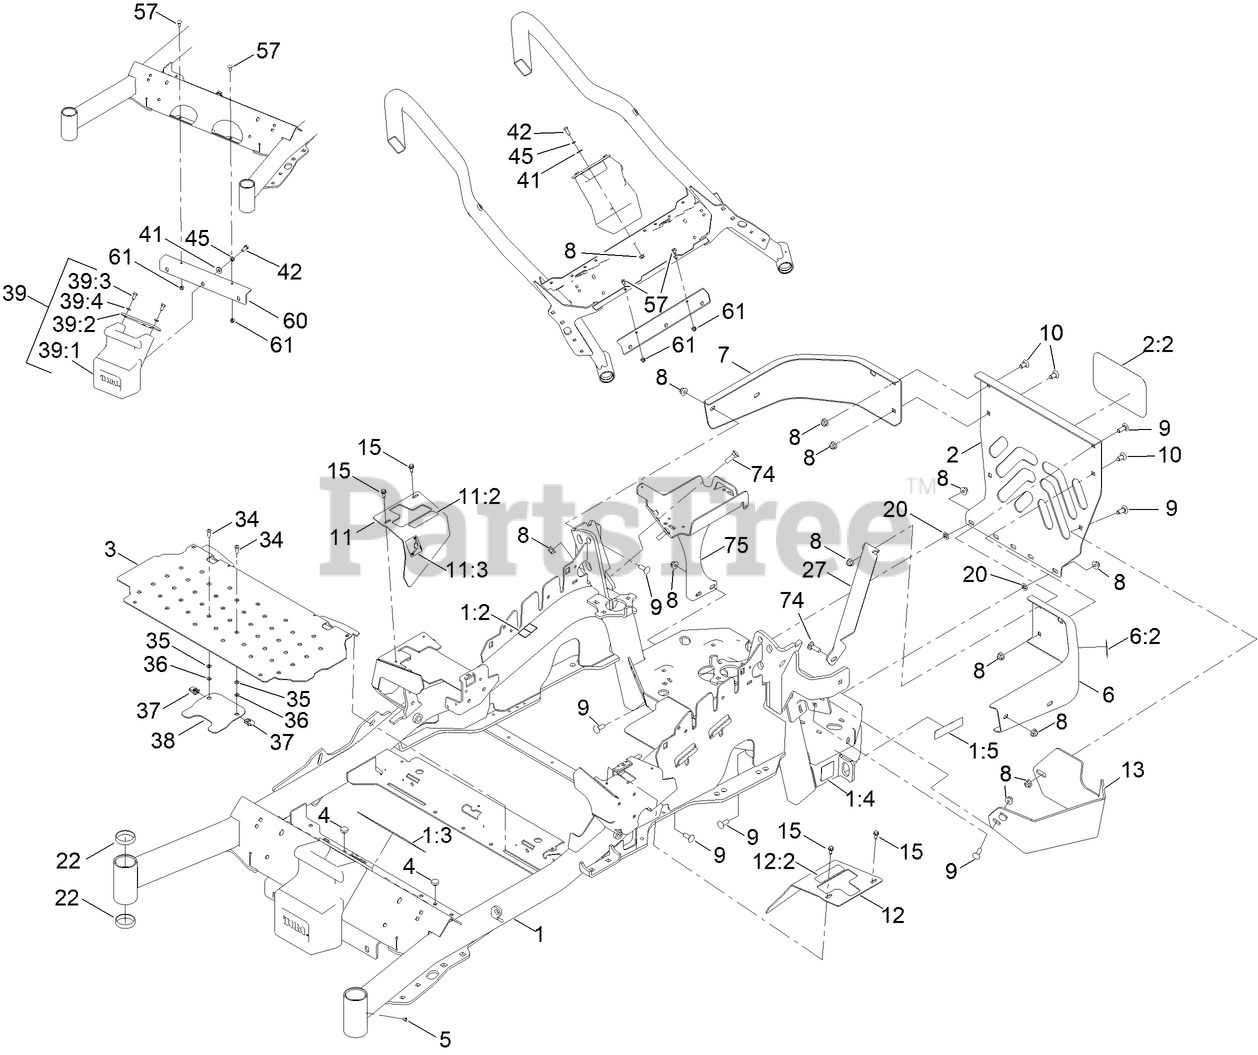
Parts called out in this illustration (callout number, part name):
1	MAINFRAME SERVICE ASM - RD
1:2	DECAL-WARNING
1:3	DECAL-DANGER
1:4	DECAL-HAZARD, PINCHED FINGER
1:5	DECAL-ARRESTOR, SPARK
2	REAR GUARD ASM
2:2	DECAL
3	FLOORPAN
4	BUMPER
6	LH BUMPER ASM
6:2	DECAL-WARNING
7	BUMPER-RH
8	NUT-HF, NI
9	SCREW-CARR
10	SCREW-CARR
11	RH MOTION CONTROL COVER ASM
11:2	DECAL-CONTROL, MOTION
11:3	DECAL-PARK BRAKE, CE
12	LH MOTION CONTROL COVER ASM
12:2	DECAL-CONTROL, MOTION
13	GUARD-MUFFLER
15	SCREW-HWH
20	NUT-PUSH
22	CUP-BEARING
34	SCREW-HSBH
35	WASHER-FLAT
36	PUSHNUT-RETAINER, BOLT
38	ADAPTER-CAPTIVE
39	WEIGHT ASM
39:1	WEIGHT-43 LB
39:2	TAB-SUPPORT, WEIGHT
39:3	SCREW-HH
39:4	WASHER-LOCK
41	WASHER-FLAT
42	SCREW-HH
45	WASHER-LOCK
57	SCREW-CARR
60	BRACKET-MOUNT, WEIGHT
61	NUT-HF, NI
74	BOLT-CARR
75	BATTERY MOUNT ASM
